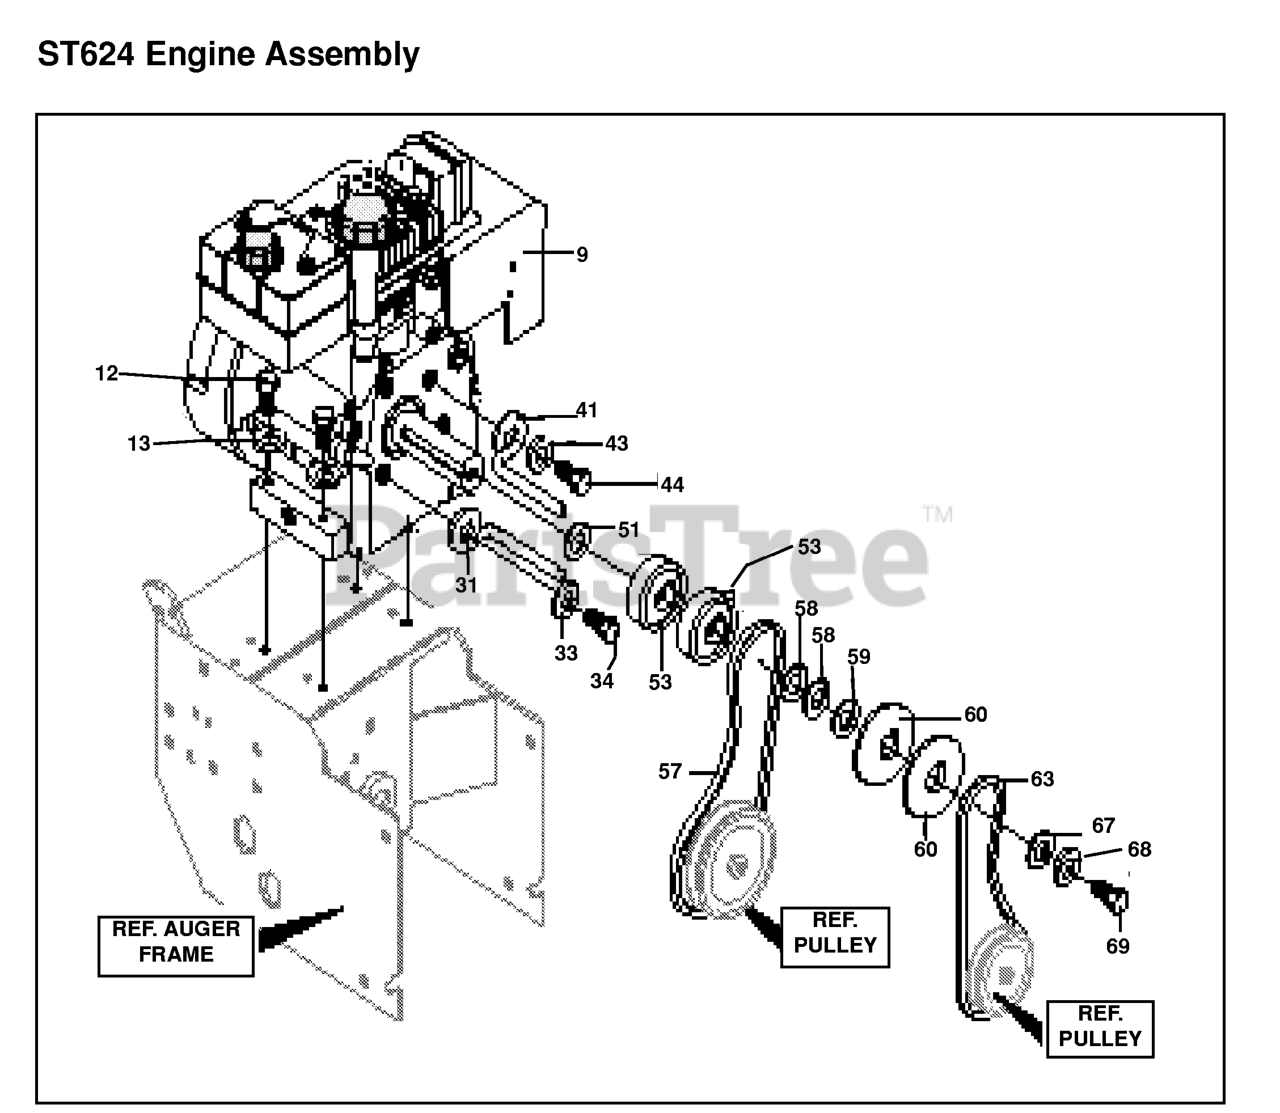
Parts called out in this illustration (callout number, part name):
12	SCREW, 5/16-18
13	WASHER, HVSPTLK .328X.60X
33	WASHER, HVSPTLK .328X.60X
43	WASHER, HVSPTLK .328X.60X
57	BELT 1733324SM
59	Spacer, Slev .753 x 1.12 x .38
60	PULLEY, ENGINE
68	WASHER, REGSPTLK.393X.68X
69	SCREW, 3/8-24X1.00 NYLHHC
